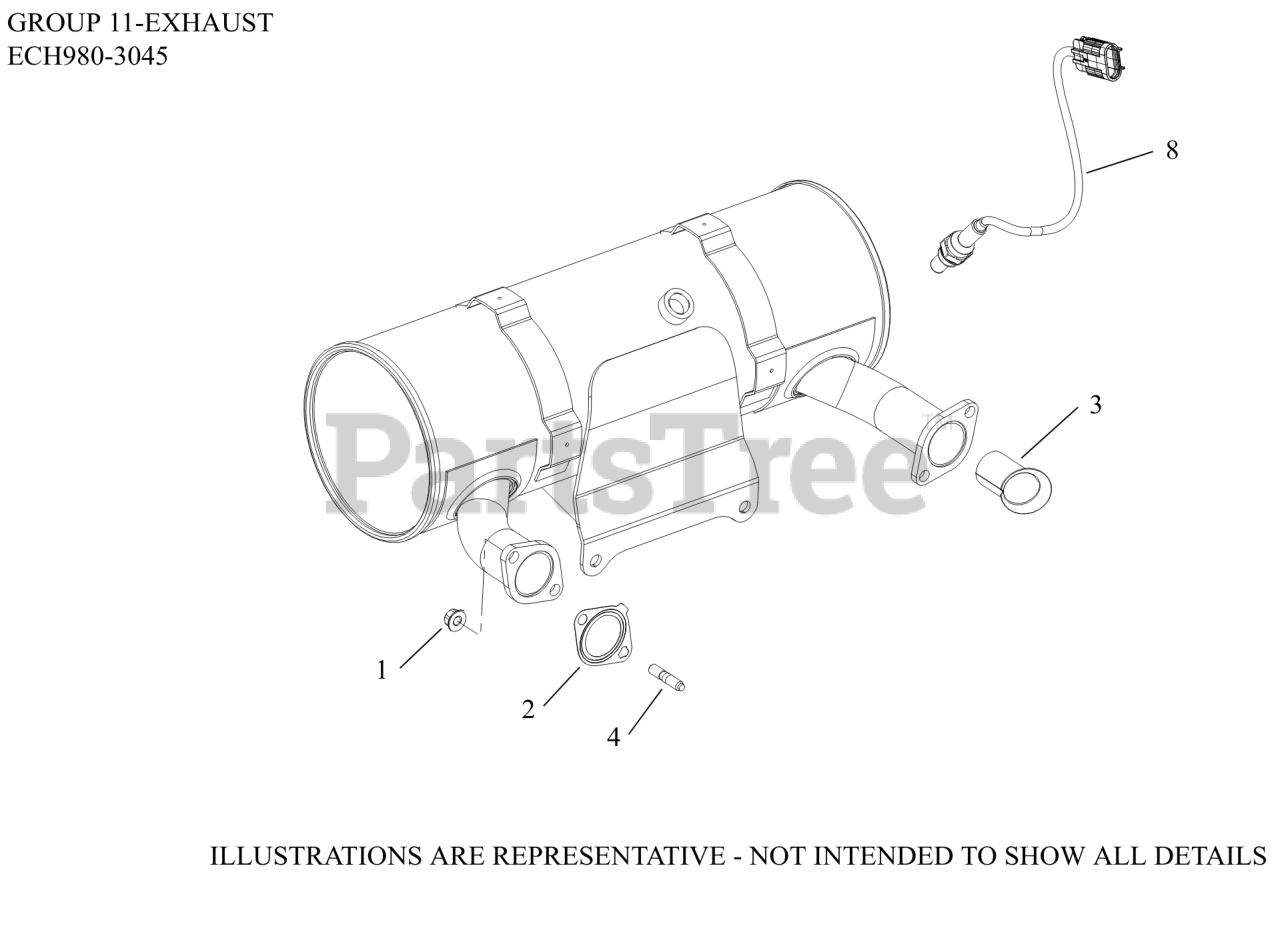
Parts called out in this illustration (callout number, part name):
1	NUT, HEX FLANGE LOCK (M8)
2	GASKET, EXHAUST
3	LINER, EXHAUST PORT
4	STUD, METRIC EXHAUST
8	SENSOR, OXYGEN (M12 x 1.25 THREADS)
